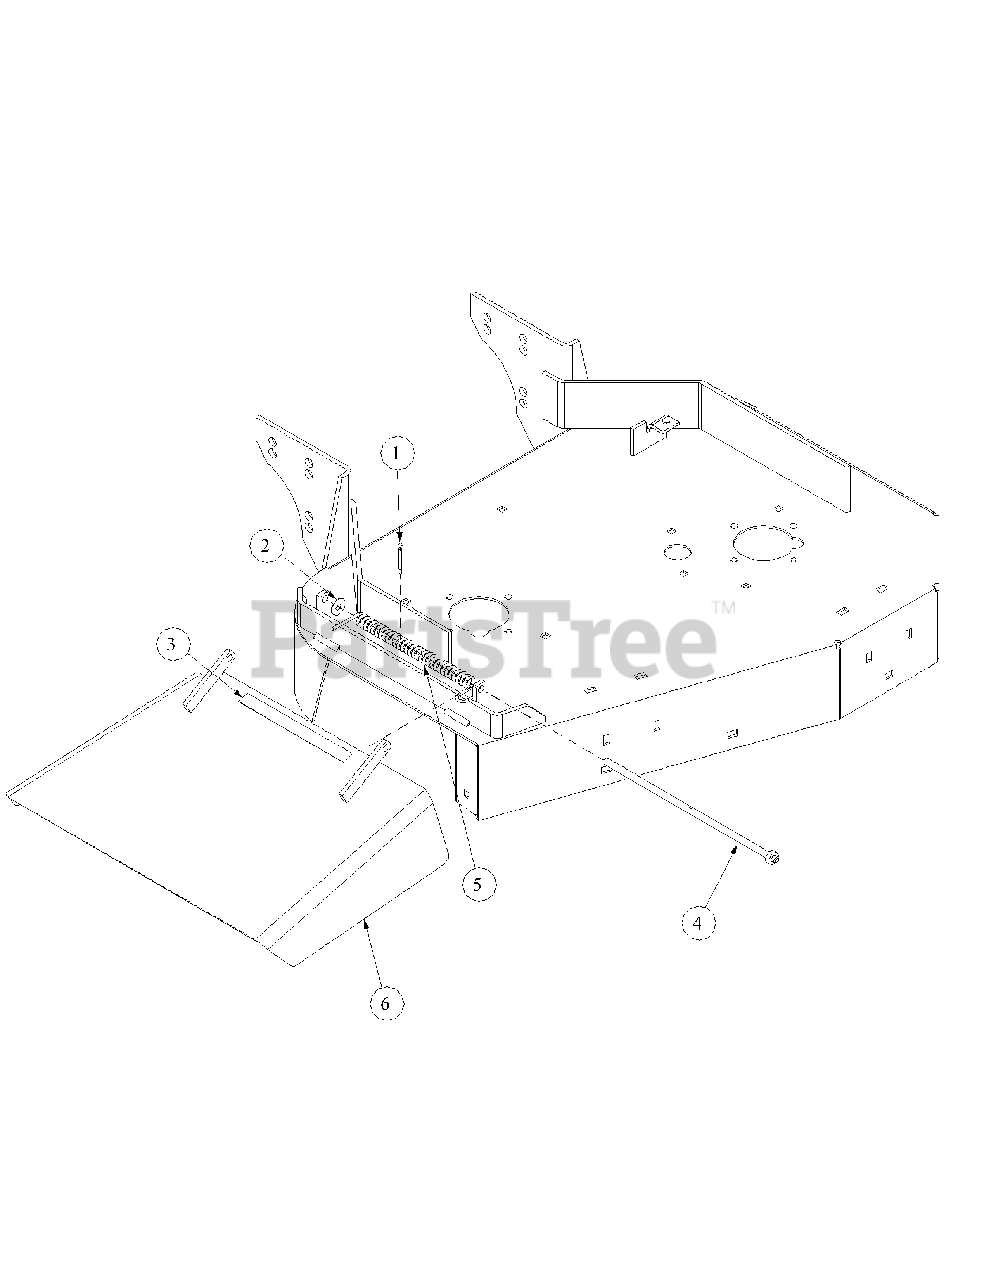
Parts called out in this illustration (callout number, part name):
1	Cotter Pin, 5/32 x 1" Lg. Zinc
2	Flat Washer, 3/8, Zinc
3	Decal, Cut Line
4	Pin, Deflector Assembly, Weldment
5	Torsion Spring
6	Chute Assembly Discharge
